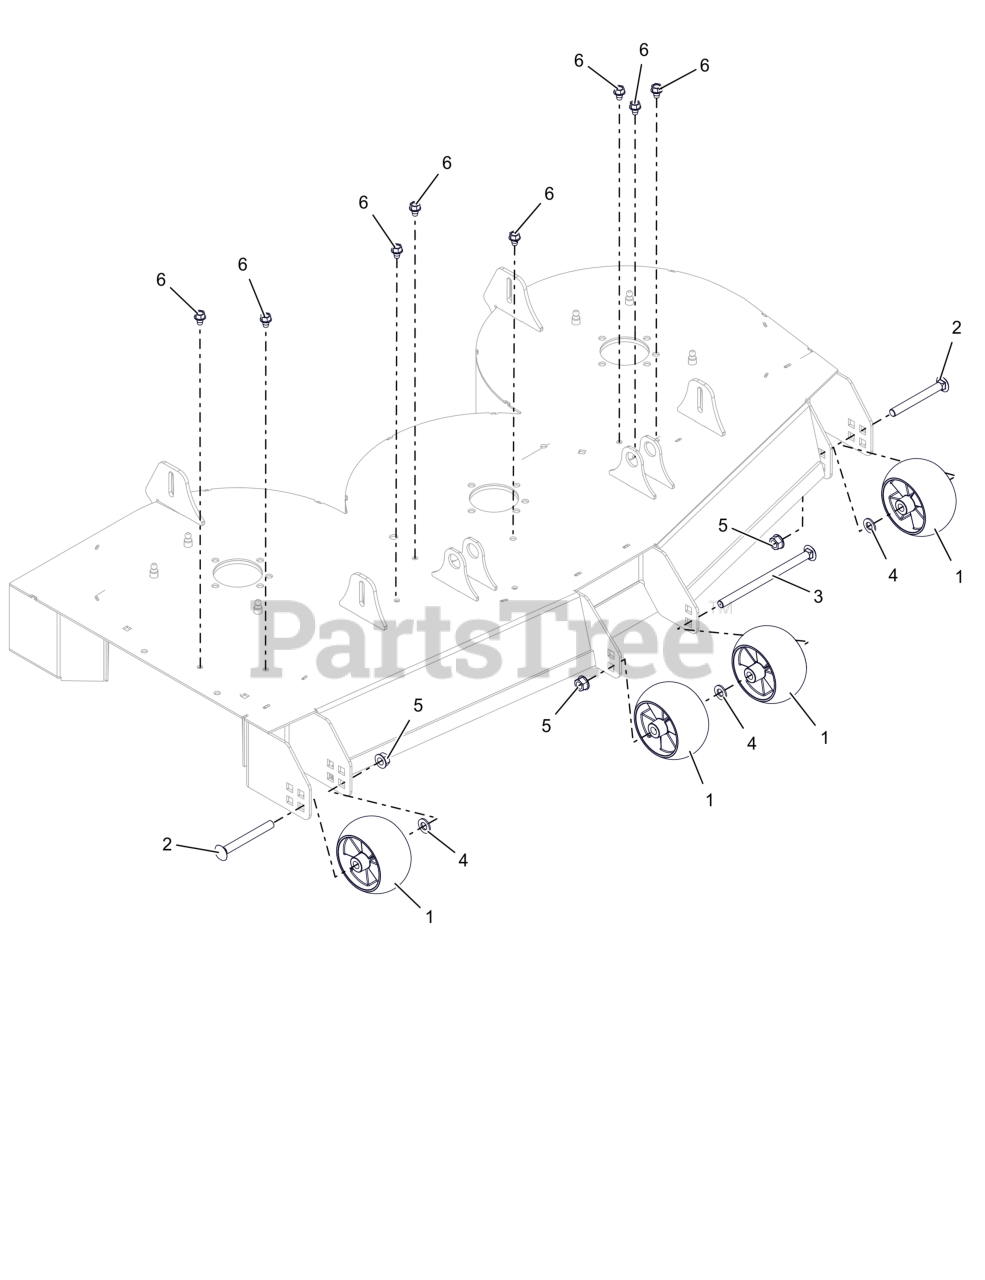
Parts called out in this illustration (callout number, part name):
1	WHEEL, ANTI SCALP - 5X3 CTR W/RIBS
2	BOLT, RHNS .50-13X4.50 G5 ZCC NS
3	BOLT, RHNS .50-13X8.00 G5 ZCC NS
4	WSHR,WAVE- TPE .525 X 1.00 X .090
5	NUT-LK-CTR-FLG .500-13 GG ZCC
6	SCR,TAP .375-16X.50 HWH TR ZCC
